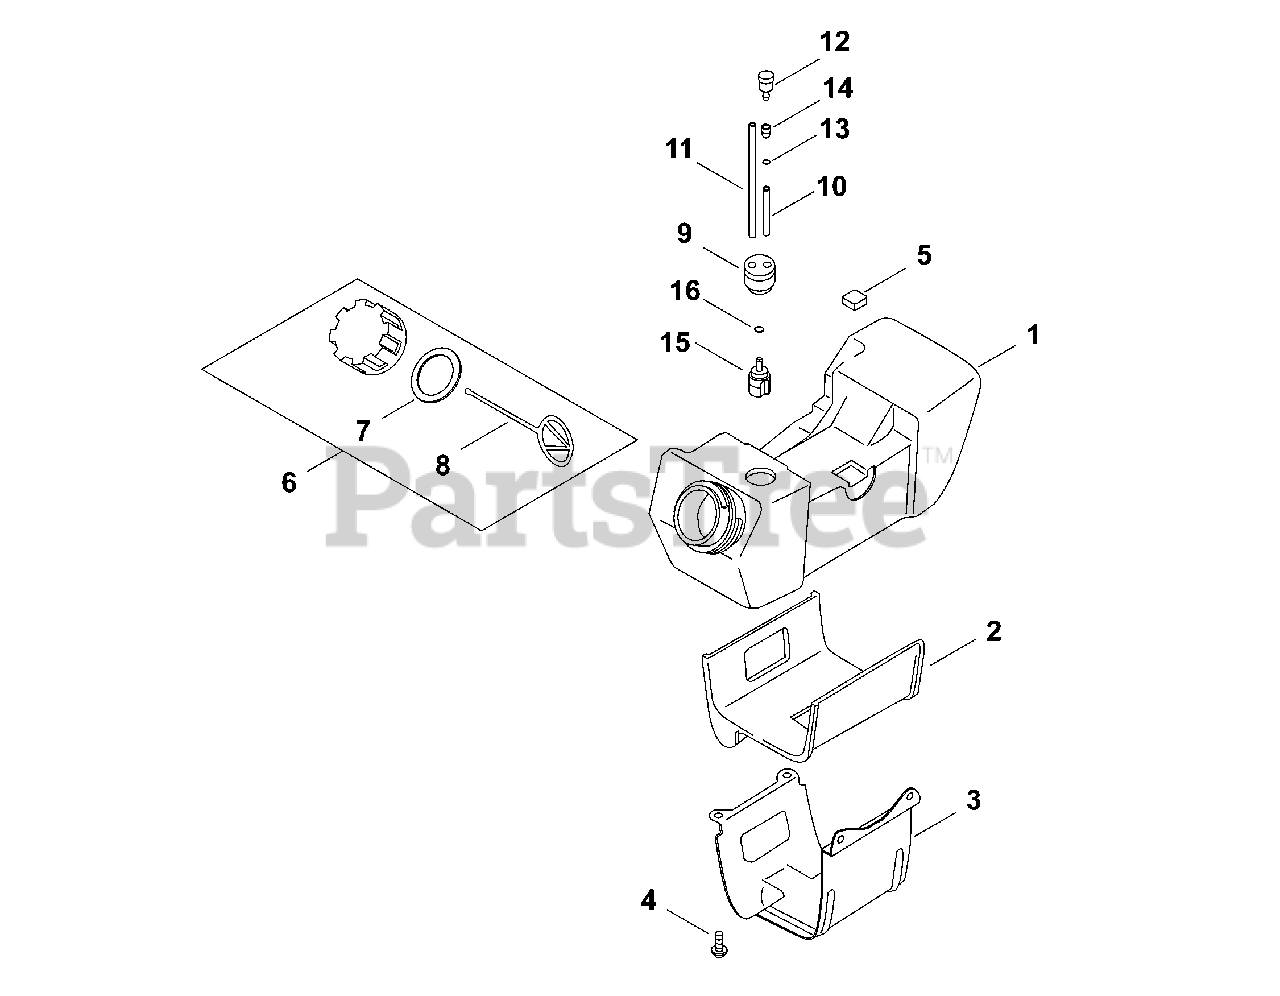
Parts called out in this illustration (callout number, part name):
1	TANK, FUEL
3	BRACKET, FUEL TANK
4	SCREW 5×14
6	CAP ASSY, FUEL
7	GASKET, FUEL CAP
8	CONNECTOR, CAP L= 100 MM
9	GROMMET, FUEL
10	PIPE 3×6×90 MM
11	PIPE, FUEL 3×5×210
12	VENT ASSY
13	CLIP Ø6.5 MM
14	HOLDER, VENT
15	FILTER, FUEL
16	CLIP Ø6
